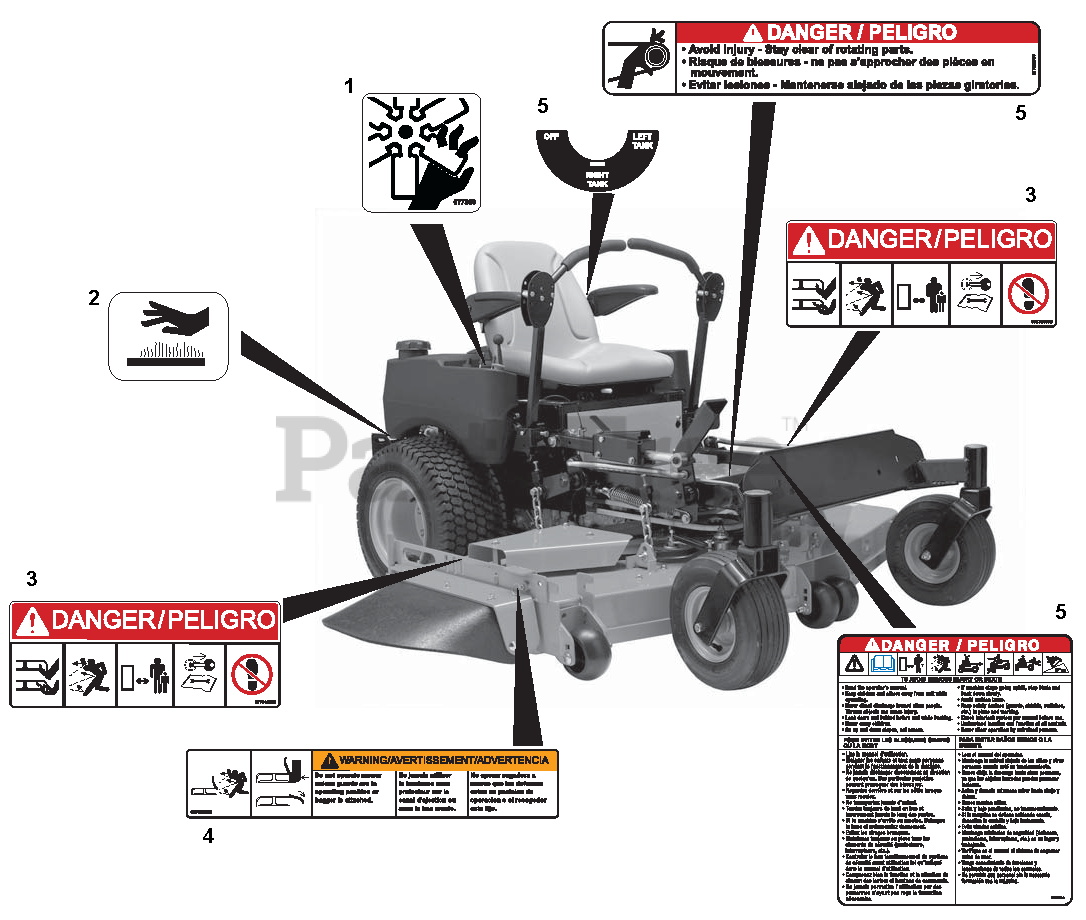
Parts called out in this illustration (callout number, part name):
1	DECAL, DANGER FAN
2	DECAL, HOT SURFACE
3	DECAL, MOWER PAN DANGER
4	DECAL, WARNING
5	SET-DECAL, COMMON DANGER/FUEL
